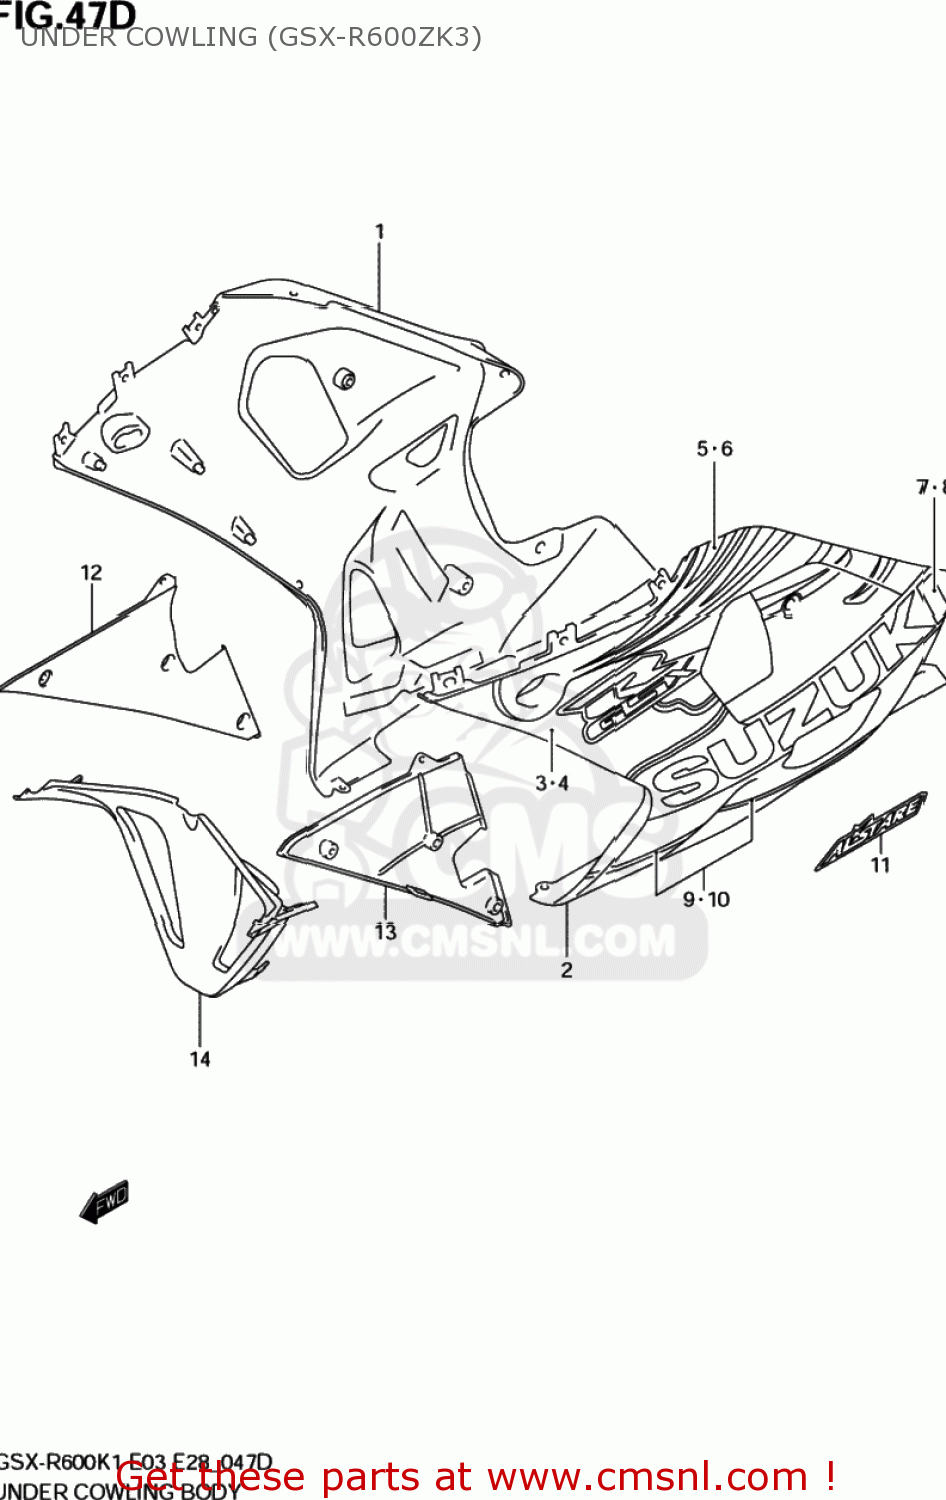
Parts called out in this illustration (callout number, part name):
1	COWLING ASSY,UNDER,R
2	COWLING ASSY,UNDER,L
3	TAPE,UNDER UPR,R
4	TAPE,UNDER UPR,L
5	TAPE SET,UNDER CTR,R
6	TAPE SET,UNDER CTR,L
7	EMBLEM SET,SUZUK,R
8	EMBLEM SET,SUZUK,L
9	TAPE SET,UNDER COWLING,R
10	TAPE SET,UNDER COWLING,L
11	EMBLEM,ALSTARE
12	COWLING,UNDER INNER,R
13	COWLING,UNDER INNER,L
14	COWLING,UNDER CTR
